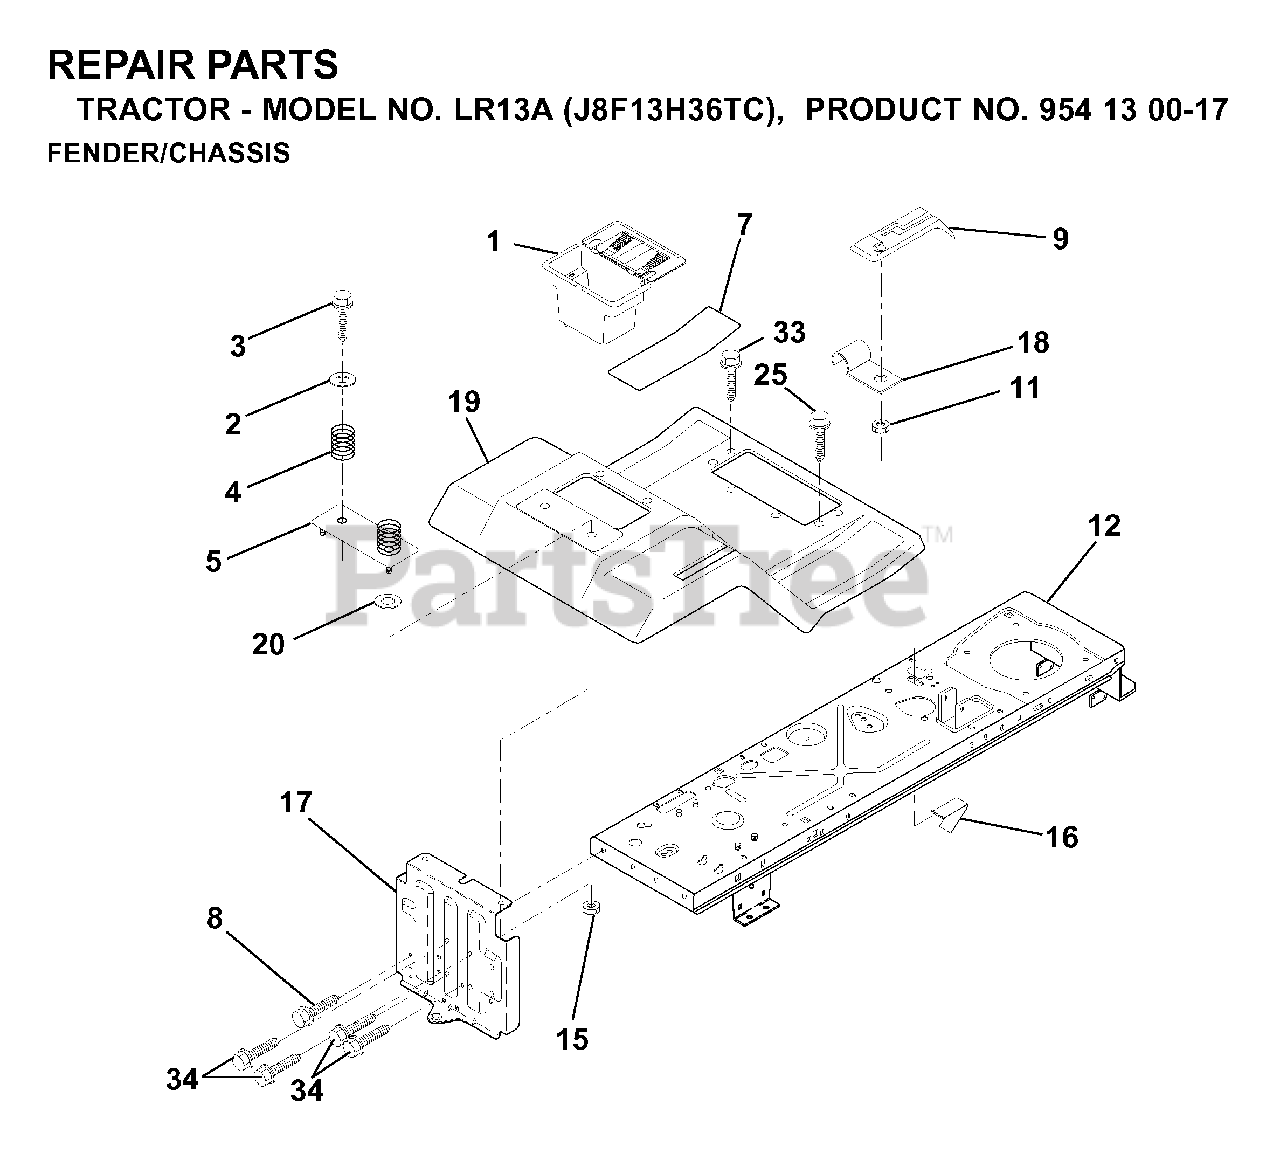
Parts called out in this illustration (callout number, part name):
1	CASE BATTERY MECH HINGE
3	SCREW
4	SPRING COMPRESSION
7	PAD FOOTREST
8	SCREW 5/16"
18	CLIP,INSULATOR
20	WASHER
34	SCREW
